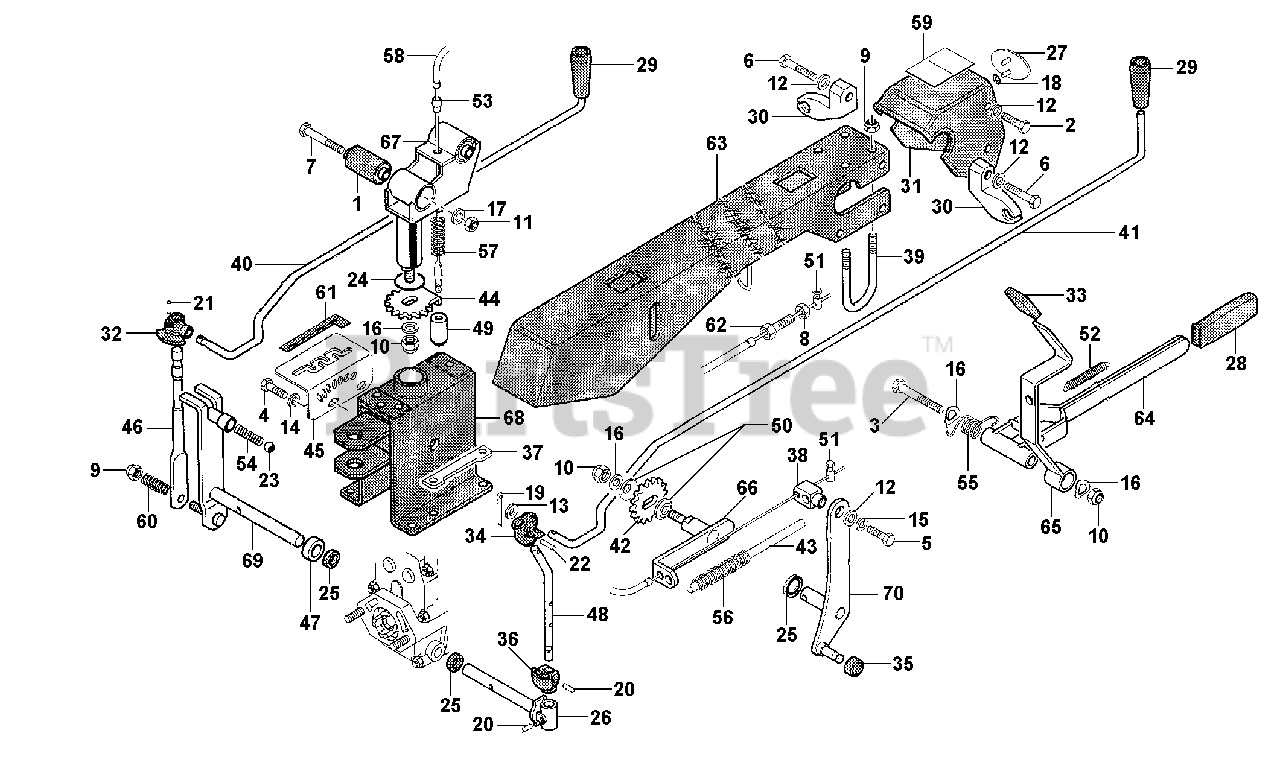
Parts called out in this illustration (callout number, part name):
1	SILENTBLOCK
2	SCREW, M8X16
3	SCREW, M10X90
4	SCREW, M8X14
5	SCREW, M8X12
6	SCREW, M8X35
7	SCREW, M12X95
9	NUT, SELF LOCKING, M8
10	NUT, SELF LOCKING, M10
11	NUT, SELF LOCKING, M12
12	WASHER, FLAT, M8.4
14	WASHER, M8.4
15	WASHER, LOCK, M8.4
16	WASHER, LOCK, M10.5
17	WASHER, LOCK, M13
18	WASHER, LOCK FOR PINS
20	LOCKING PIN, M4X20 SPIRAL
21	PIN, LOCKING, M3X22 SPIRAL
22	LOCKING PIN, M4X24 SPIRAL
23	BALL 15/32 RIV RB-11.906
24	O-RING, M28.17X3.53
25	OIL SEAL, M14X22X4
30	SUPPORT CONTROL ROD CUT
31	STEERING COLUMN INTERM. PANEL
32	GEARBOX ARTICULATION
33	KNOB REDUCTION UNIT LEVER
34	PTO ARTICULATION
35	PTO LOCKOUT RING
36	PTO STOP RING
37	REVERSE SPEED LEVER DOG
38	REVERSE BLOCK
39	HANDLEBAR U-BOLT
40	GEARBOX CONTROL ROD
41	PTO CONTROL ROD
42	REVERSE GEAR
44	BENDED REVERSER GEAR
45	GEAR QUADRAINT
48	PTO CONTROL LEVER
49	PUSH ROD D=8
50	PROTECTION END D 32
51	CLAMP, CABLE
55	HANDLEBAR RELEASE SPRING
56	REVERSER SPRING
57	PUSH ROD SPRING
58	STEERING COLUMN CABLE
59	STEERING COLUMN STICKER
62	ADJUSTING SCREW
63	STEERING COLUMN
64	HANDLEBAR RELEASE LEVER
65	STEERING COLUMN LOCKING LEVER
66	REVERSER POSTION LEVER
67	STEERING COLUMN COUPLING
68	STEERING COLUMN SUPPORT
69	SPEED SELECTOR LEVER
70	REVERSER LEVER
